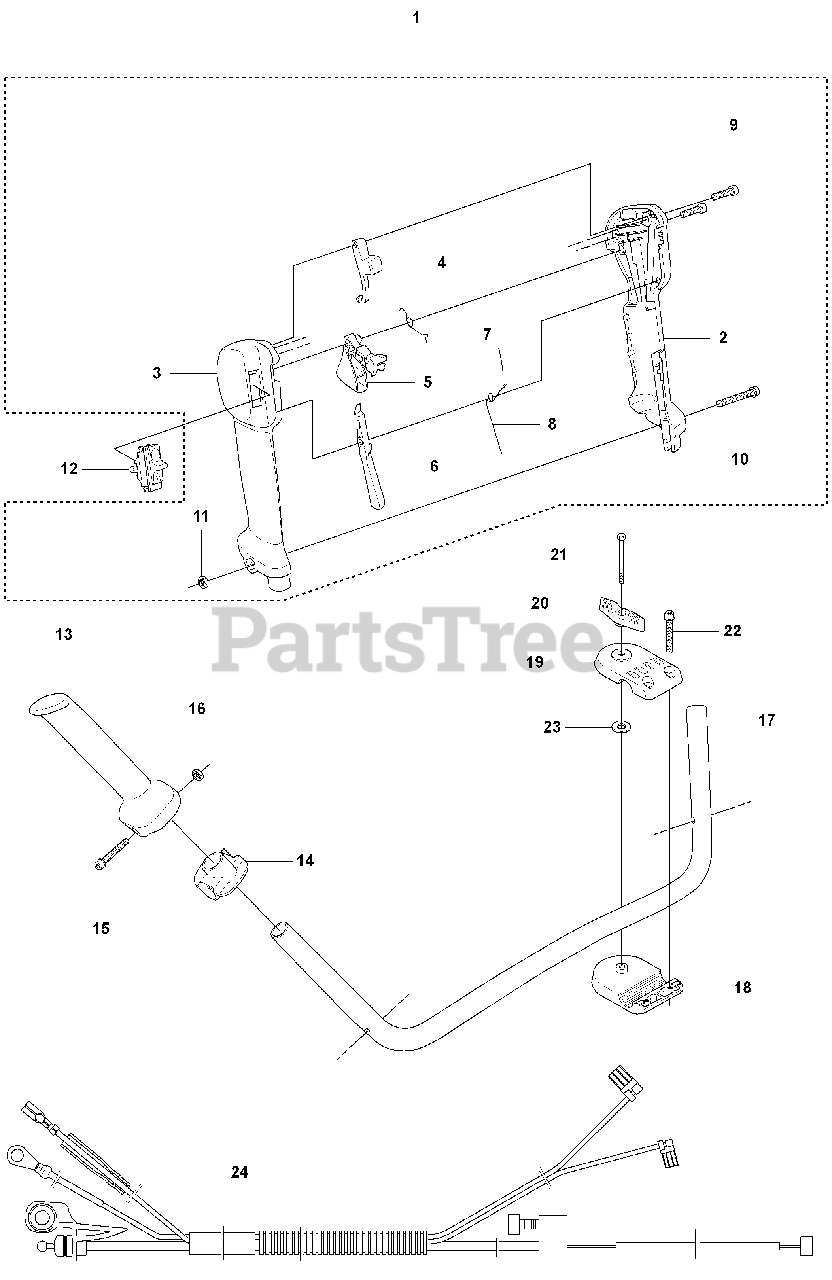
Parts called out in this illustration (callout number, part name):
2	HANDLE HALF RIGHT
3	HANDLE HALF LEFT
4	LOCKOUT STARTER THROTTLE
5	%THROTTLE TRIGGER
6	%THROTTLE LOCK
10	%SCREW
12	STOP BUTTON
16	NUT M6M M5
17	HANDLE
18	HANDLE HOLDER LOWER
19	HANDLE HOLDER UPPER
21	%SCREW
